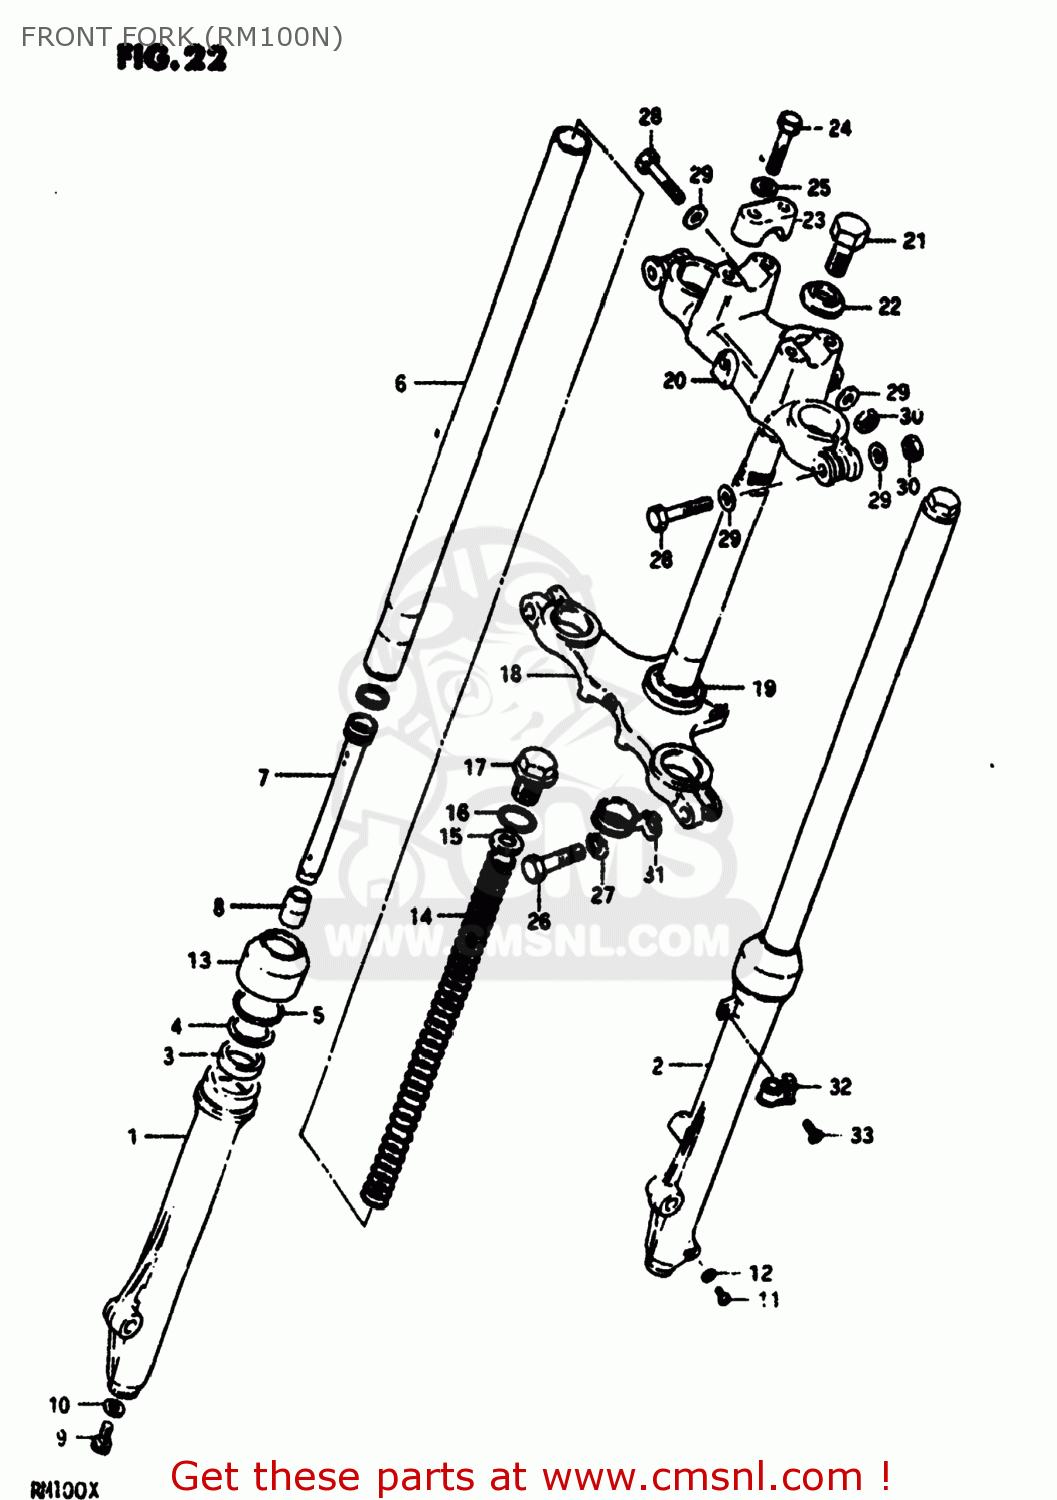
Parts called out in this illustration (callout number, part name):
1	TUBE,OUTER,RIGHT
2	TUBE,OUTER,LEFT
3	SEAL,OIL
4	RING,FORK BACK UP
5	CIRCLIP,FORK OIL SEAL
6	TUBE,FORK,INNER
7	CYLINDER,FRONT FORK
8	PIECE,OIL LOCK
9	BOLT,FORK CYLINDER(10X25)
10	GASKET (NAS)
11	SCREW
12	GASKET,DRAIN,PLUG (NAS)
13	SEAL,DUST
14	SPRING
15	GUIDE,FRONT FORK SPRING C
16	O RING
17	CAP,FORK INNER TUBE
18	STEM,STEERING
19	RACE,STEERING,OUTER,UPPER
20	HEAD,STEERING STEM
21	BOLT
22	WASHER
23	HOLDER,HANDLEBAR
24	BOLT
25	LOCK WASHER
26	BOLT
27	WASHER,LOCK 12
28	BOLT 8X55
29	WASHER
30	NUT 8MM
31	GUIDE,CABLE
32	CLIP,CABLE
33	SCREW
